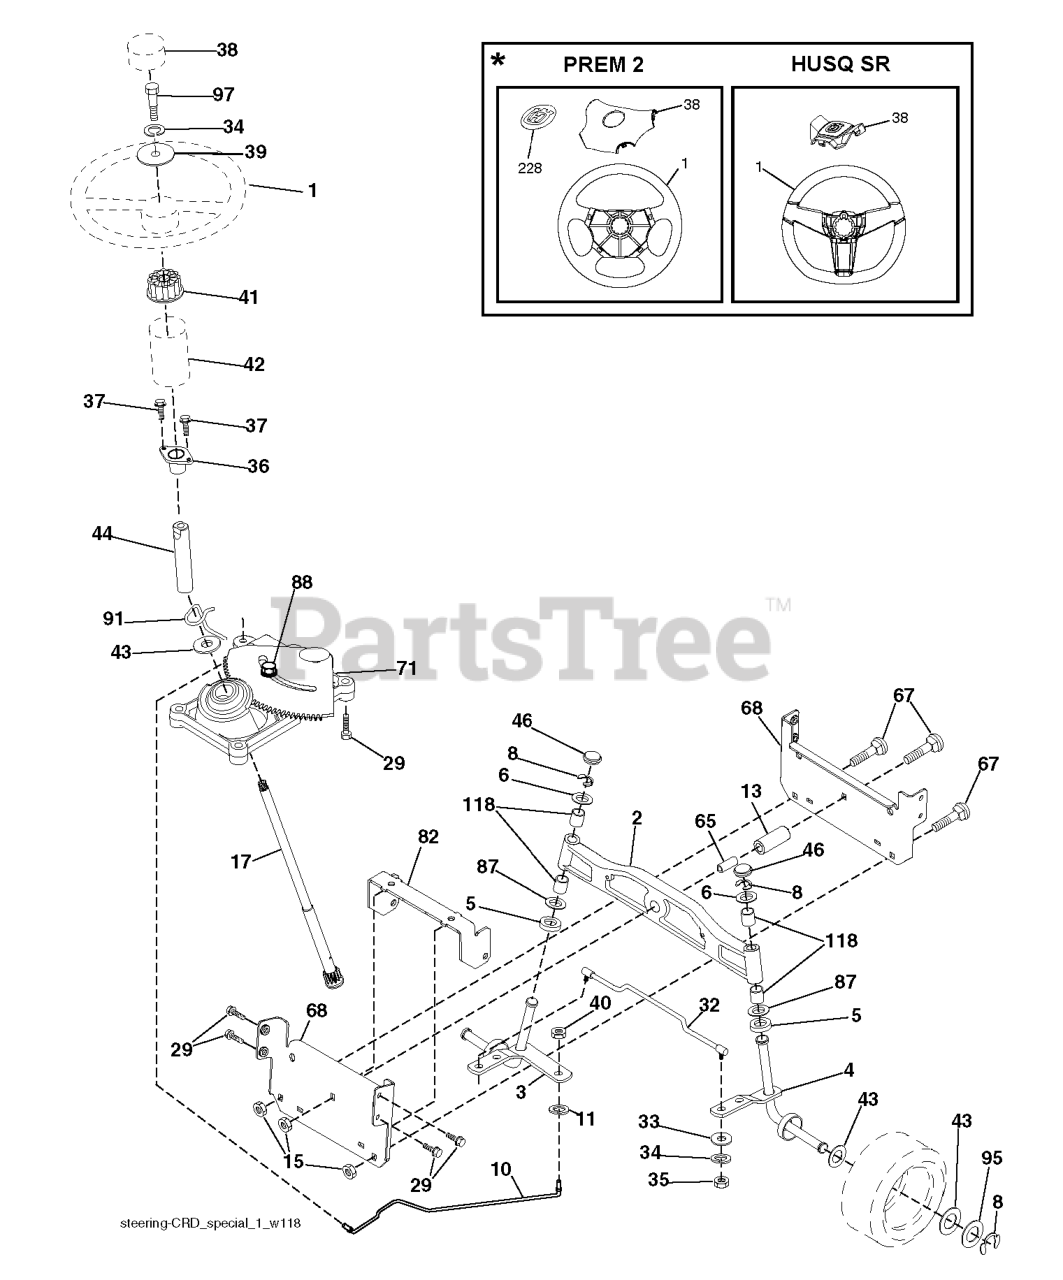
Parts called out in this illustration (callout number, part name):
1	RP WHEEL.STEER.HUSQ.PREM.OVMLD
2	AXLE.ASM.LT.CAST.LGHTWGHT
3	SPINDLE.ASM.LH.15"TIRES
4	SPINDLE.ASM.RH.15"TIRES
5	THRUST WASHER
10	DRAGLINK.15".TIRES.2001
11	WASHER, LOCK 3/8
13	TUBE, PIVOT AXLE
15	NUT
17	SHAFT STEERING SPLINE
29	SCREW, 3/8-16X3/4
33	WASHER M
34	WASHER.LOCK.HVY.HLCL.SPR.5/16
35	NUT, CROWNLOCK
36	BUSHING, STEERING
37	SCREW.TT.#10-32X.5.3/8.FLANGE
38	RP INSERT.CAP.WHL.STRG.HUSQ.
39	WASHER.11/32
40	NUT CROWNLOCK 3/8-24
41	ADAPTER, WHEEL STNG..
42	BOOT, STEERING
44	SHAFT.EXTEN.STRG.SPLINE
46	CAP.SPINDLE.BLACK
65	SPACER.BRACE.AXLE
67	BOLT CARRIAGE
68	BRACE.AXLE.15"TIRES
71	STEERING ASM
82	BRACKET.SUSP.CHASSIS.FRONT.15
87	WASHER, FLAT .781 X 1 1/2"
88	BOLT, SHOULDER 7/16-20
91	CLIP.STEERING
95	WASHER.HARDENED
118	BUSHING, AXLE CAST
228	DECAL.WHEEL.STRG.LGN.H
